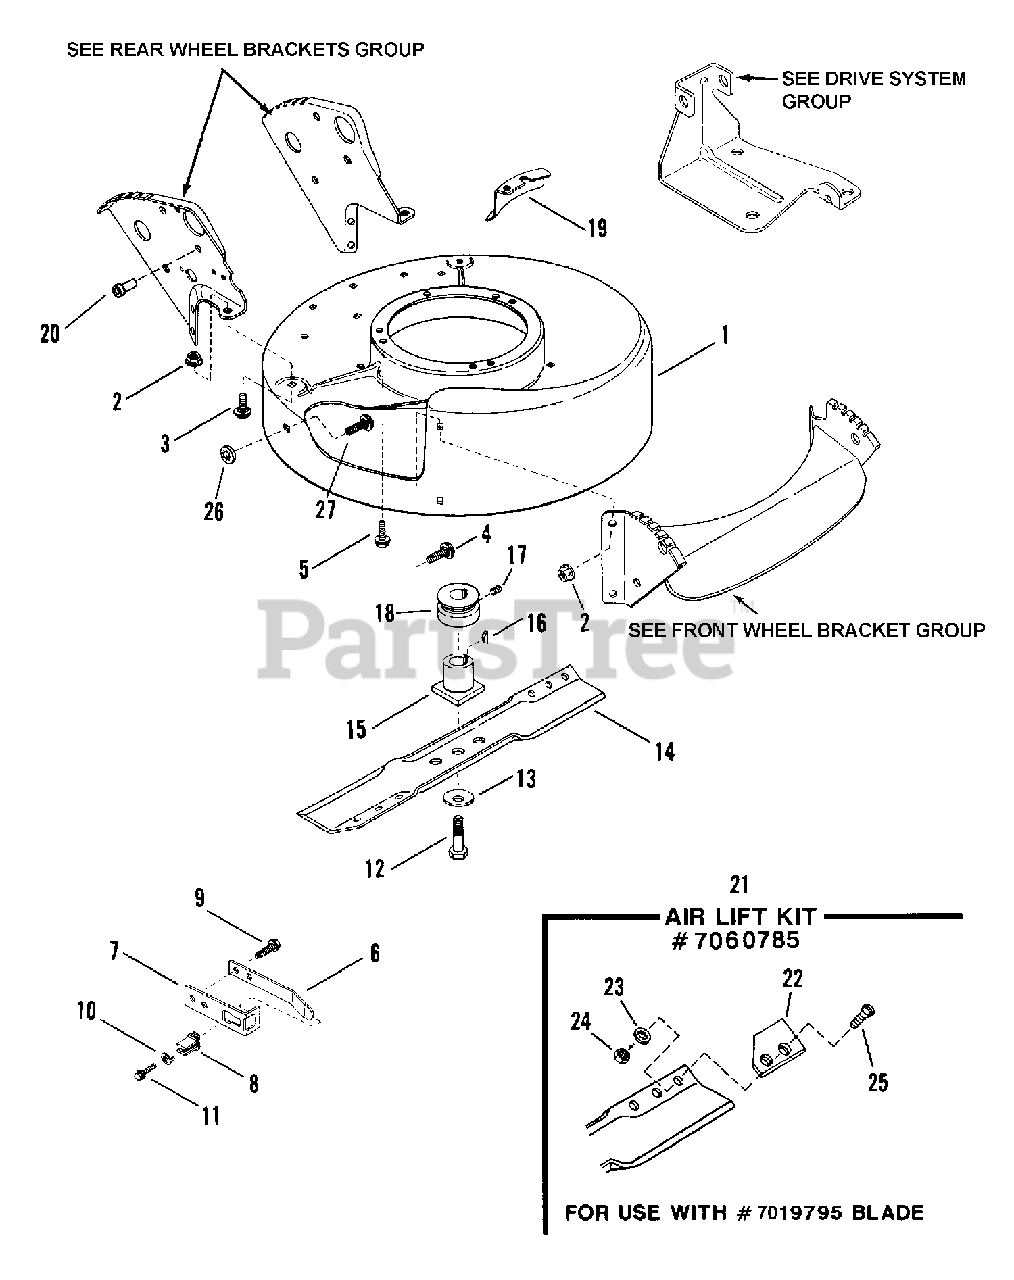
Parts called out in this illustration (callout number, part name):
1	DECK, Mower
2	NUT, 5/16-18 Hex Flange Lock
3	BOLT, 5/16-18 x 1/2" Short Neck Carriage (Gr.)
4	BOLT, 5/16-18 x 1" Short Neck Carriage
5	SCREW, 3/8-16 x 1" Self-tapping (Engine Mounting)
6	SPRING, Wheel Bracket Type Interlock
7	BRACKET, Wheel Bracket Type Interlock
8	INSULATOR, Interlock
9	SCREW, 1/4-20 x 1/2" Self-tapping
10	WASHER, #8 Tab Internal Tooth Lock
11	SCREW, #8-18 x 3/4" Hex Head Machine
12	SCREW, 3/8-24 x 2" Hex Head Cap (Gr. 5)
13	WASHER, Cone
14	BLADE, Cutter
15	HUB, Blade Drive (7/8" Dia. I.D.)
15	HUB, Blade Drive (25mm Dia. I.D.)
16	KEY, Hi-Pro
16	KEY, Woodruff (Briggs)(Tecumseh 2 Cycle)
16	KEY, Square (Robin & Tecumseh)
17	SCREW, 5/16-18 x 5/16" Hex Socket Set
18	PULLEY, Engine (Briggs 3.5 H.P.) (7/8" I.D. x 1-7/8" O.D.)
18	PULLEY, Engine (Briggs) (Tecumseh 2 Cycle) (25mm I.D. x 2-1/8" O.D.)
18	PULLEY, Engine (Tec. & Robin) (25mm I.D.x 2-1/8" O.D.)
19	SHIELD, Belt Opening Cover
20	BUSHING, Interlock Wire
21	KIT, Air Lift
22	LIFT, Air
23	WASHER, 5/16 Internal Tooth Lock
24	NUT, 5/16-24 Hex
25	SCREW, 5/16-24 x 11/16" Machine
26	RETAINER, 5/16 Bolt
27	BOLT, 5/16-18 x 5/8" Carriage
